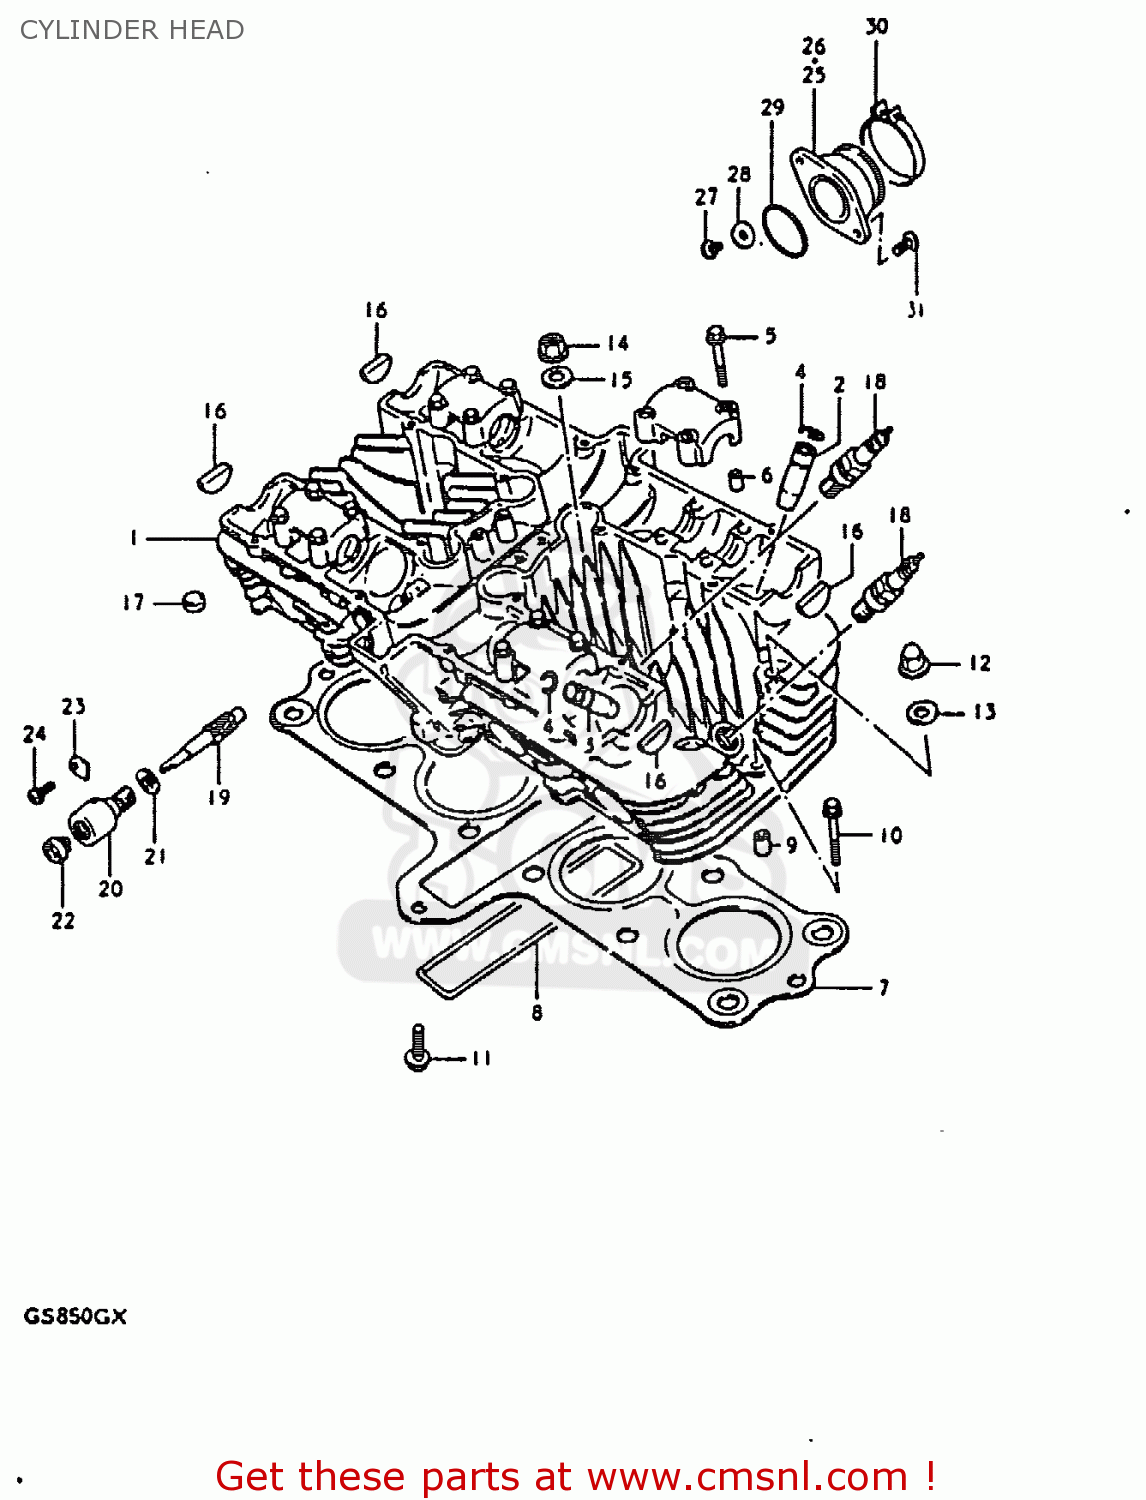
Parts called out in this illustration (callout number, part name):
1	HEAD ASSEMBLY,CYLINDER
2	GUIDE,INTAKE VALVE
3	GUIDE,EXHAUST VALVE
4	RING,SNAP
5	BOLT(6X39)
6	PIN(6.2X8X11)
7	GASKET,CYLINDER HEAD (MCA)
8	O RING(D:3,ID:26X157)
9	PIN
10	BOLT,UNDER
11	BOLT
12	NUT
13	GASKET (NAS)
14	NUT
15	WASHER(10.5X22X2.3)
16	PLUG
17	PAD
18	SPARK PLUG
19	GEAR,TACHOMETER DRIVEN
20	SLEEVE,TACHOMETER DRIVE
21	SEAL,TACHOMETER DRIVEN
22	SEAL,OIL(5X12X8)
23	PLATE,TACH DRIVE GEAR SLEEVE
24	SCREW(5X12)
25	PIPE,INTAKE,R
26	PIPE,INTAKE,L
27	BOLT
28	GASKET(5.3X9.3X1.2) (NAS)
29	O-RING
30	CLAMP
31	SCREW
